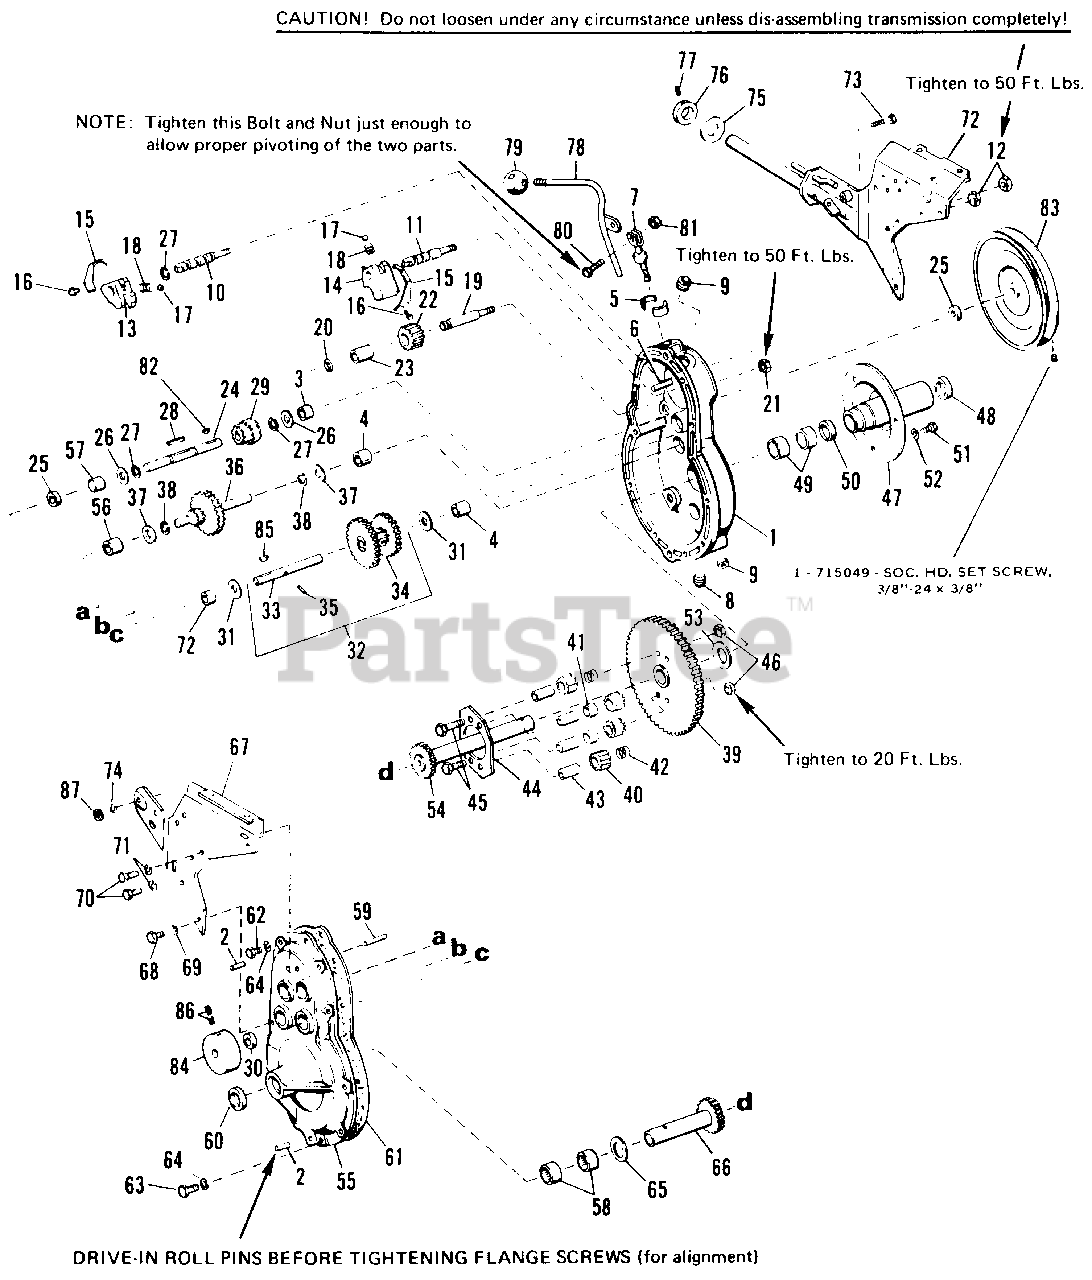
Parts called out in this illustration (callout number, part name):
1	Gear Case w/Bearing-Pins Bushings (Includes 2, 3, 4, 5, 6 & 7)
2	Pin, Roll
3	Bearing, Roller
4	Bearing, Roller
5	Bushing, Ball Half
6	Roil Pin Assembly
7	Rod Assembly, Shift
8	Plug, Pipe
10	Shaft, Shift, Rev.-Lo
11	Shaft, Shift, Hi-Lo
12	Nut, Hex, Full, 7/16"-14
13	Fork, Shift, Rev.
14	Fork, Shift, Hi-Lo
16	Capscrew, Hex, 5/16"-18 x 5/16" lg.
17	Ball, Shift, Lock
19	Shaft, Rev., Pinion
21	Nut, Hex Full, 7/16"-14
22	Pinion, Rev.
23	Bearing, Roller
24	Shaft, Pulley, P.T.O.
27	Ring, Retaining
29	Pinion Assembly, Hi-Lo
32	Shaft & Gear Assembly
33	Shaft, Brake
34	Gear Assembly, Cluster
35	Pin, Dowel
36	Gear & Shaft Assembly
38	Ring, Retaining
39	Gear Assembly, Drive
40	Pinion, Diff.
41	Spacer, Diff.
42	Spring, Diff.
43	Spindle, Pinion, Diff.
44	Plate, Diff.
45	Capscrew, Hex, 3/8"-16 x 2-1/2" lg.
46	Nut, Hex, Full, Lock, 3/8"-16
47	Housing Assembly Axle
49	Bearing, Roller
51	Capscrew, Hex, 3/8"-16 x 7/8" lg.
52	Lockwasher, 3/8"
54	Axle Shaft Assembly R.H.
55	Gear Case
56	Bearing, Roller
57	Bearing, Roller
58	Bearing, Roller
59	Roll Pin assembly
61	Gasket, Case
62	Capscrew, Hex, 5/16"-18 x 1-1/4" lg.
63	Capscrew, Hex, 5/16"-18 x 1-1/2" lg.
64	Lockwasher, 5/16"
66	Axle Shaft Assembly, L.H.
67	Plate, Side, Trans., L.H.
68	Capscrew, Hex, 3/8"-16 x 3/4" lg.
69	Lockwasher, 3/8"
70	Capscrew, Hex, 7/16"-14 x 1" lg.
71	Lockwasher, 7/16"
72	Plate Assembly, Side, Trans., R.H.
73	Capscrew, Hex, 3/8"-16 x 1-3/4" lg.
74	Lockwasher, 3/8"
76	Collar, Set
77	Screw, Set, Sq. Hd. 5/16"-18 x 1/2" lg.
78	Rod Assembly, Shift
80	Capscrew, Hex, 1/4"-20 x 3/4" lg.
81	Nut, Hex, Full, Lock, 1/4"-20
83	Pulley, Transmission
84	Drum, Brake
86	Screw, Set, 5/16"-18 x 3/4" lg.
87	Nut, Hex, Full, 3/8"-16
